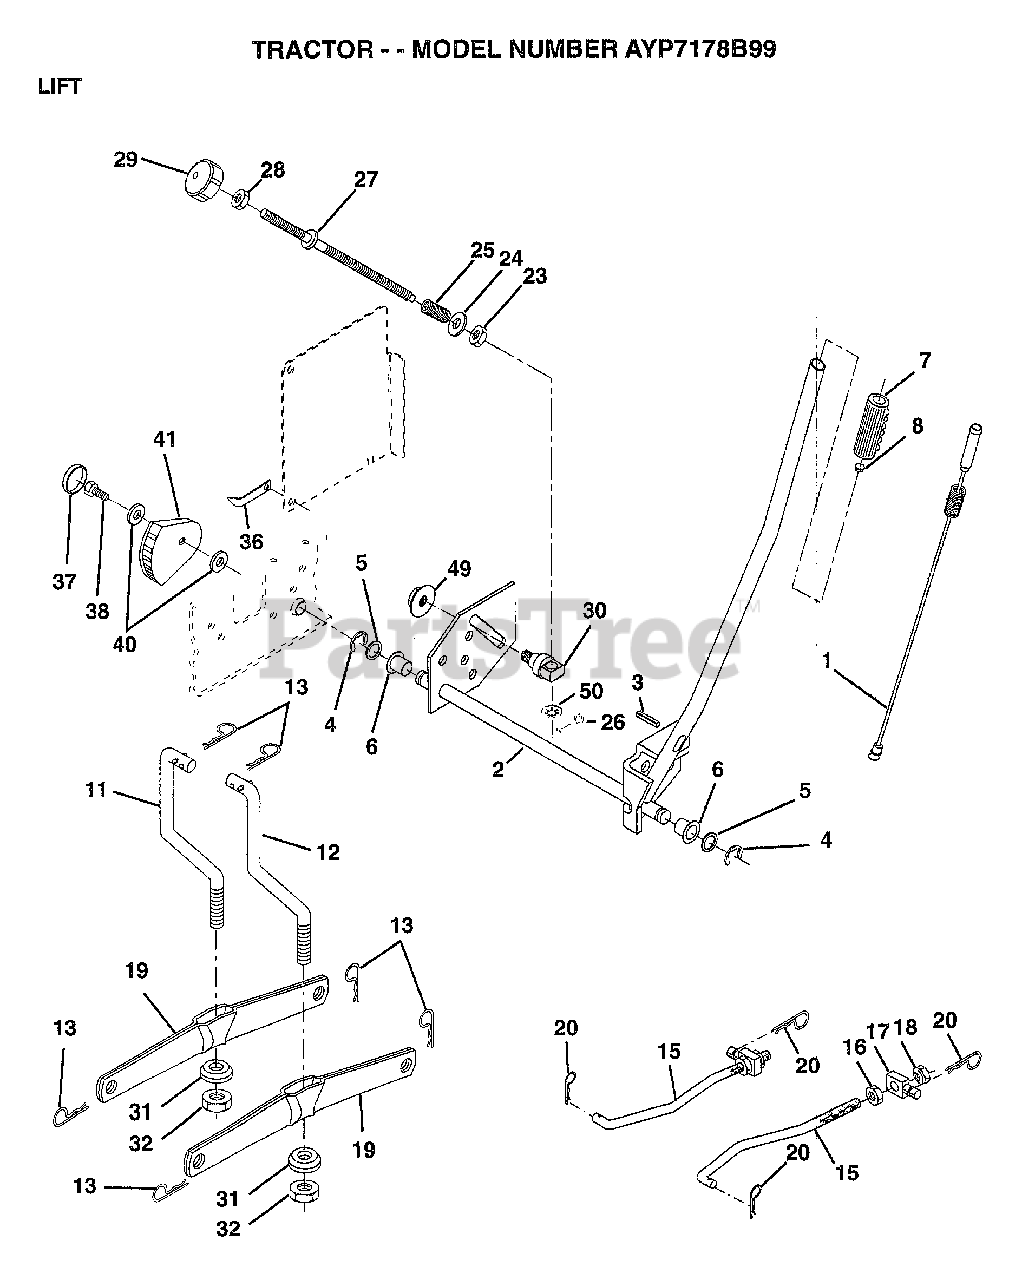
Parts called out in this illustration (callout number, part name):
1	WIRE ASM W.SPRING
2	SHAFT ASM LIFT RH
3	PIN-GROOVE LT
5	WASHER
6	NYLON BEARING
7	GRIP HANDLE
15	LINK.FRONT
16	NUT
17	TRUNION
18	NUT.LK.W/WSH.1/2.
19	ARM SUSP REAR
20	RETAINER SPRING
23	NUT T
24	WASHER
25	SPRING T
28	NUT
29	KNOB INF 3/8-16
30	TRUNNION
31	BEARING PVT LH
32	NUT.CROWNLOCK.3/8
36	POINTER-INDICAT
37	"PLUG,HOLE"
38	SCREW
40	WASHER
41	INDICATOR HEIGHT
49	NUT.HXFLG.LOCK.
50	NUT PUSH M
